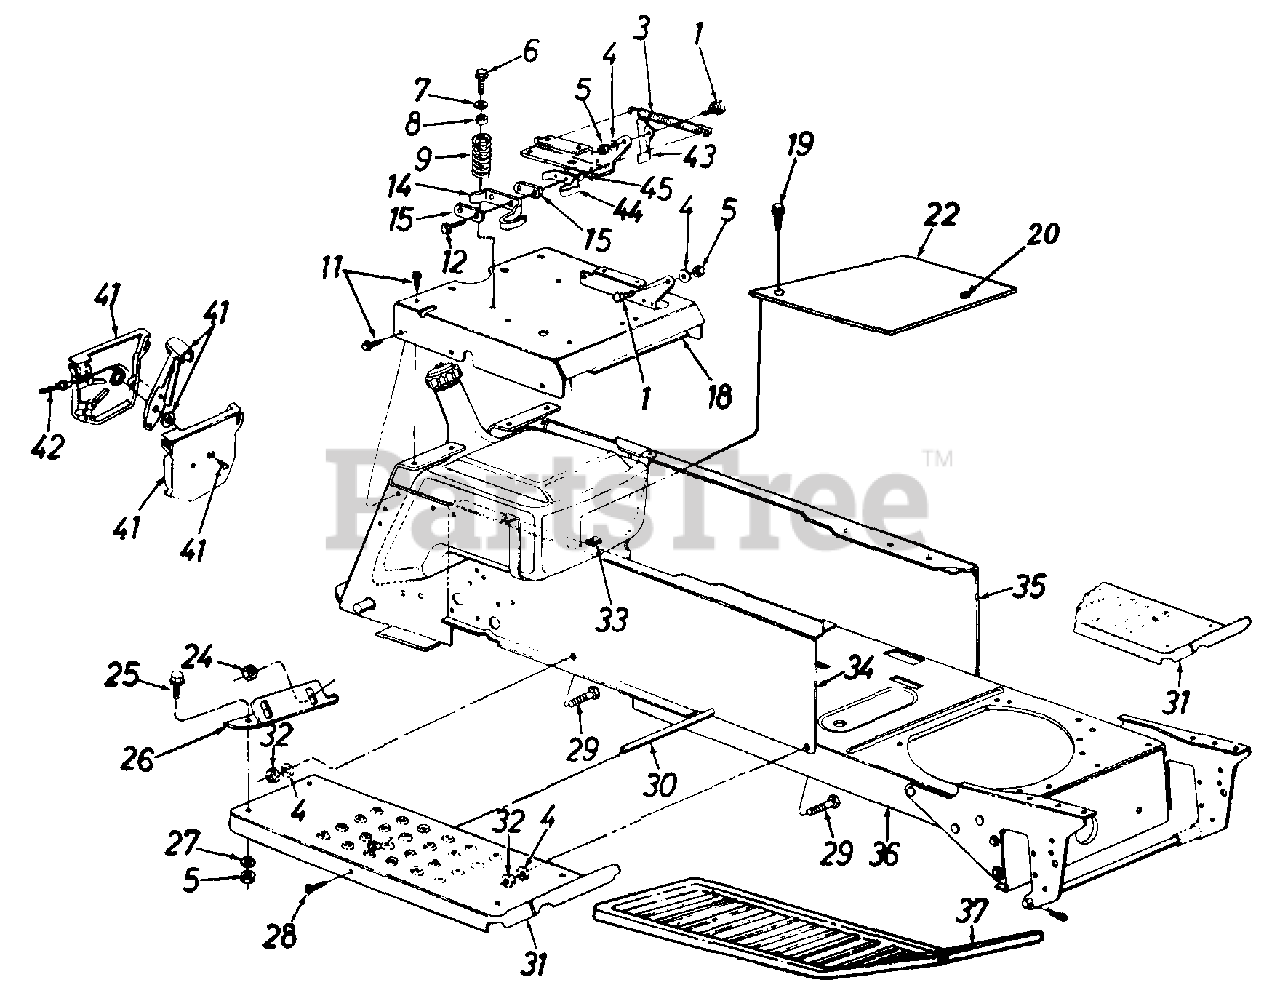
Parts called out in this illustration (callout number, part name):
1	Shld. Bolt .437" Dia. x .162"
3	Ext. Spring 5.31" Lg.
4	L-Wash. 5/16" I.D.
5	Hex Nut 5/16-18 Thd.
6	Hex Wash. Hd. Tap Scr.
7	Fl-Wash. .344" I.D.
8	Bushing
9	Compression Spring
11	Hex Wash. Hd. AB-Tap Scr.
12	Hex Wash. Hd. AB-Tap Scr. #8 x .5
14	Spring Switch
15	Insulator Plate
18	Seat Plate
19	Truss Mach. B-Tap Scr. #10 x .5" Lg.
20	Snap Bushing
25	Hex Bolt 5/16-18 x .75" Lg.
28	Truss Mach. Scr. 5/16-18 x .75" Lg.
29	Rib Neck Bolt 5/16-24 x .75" Lg.
30	Running Board Rod
33	Speed Nut #102
41	Throttle Control Box Ass'y.
42	Throttle Control Wire 39" Lg.
43	Seat Lift Bracket
44	Seat Spring Switch
45	Insulator Boss Plate
